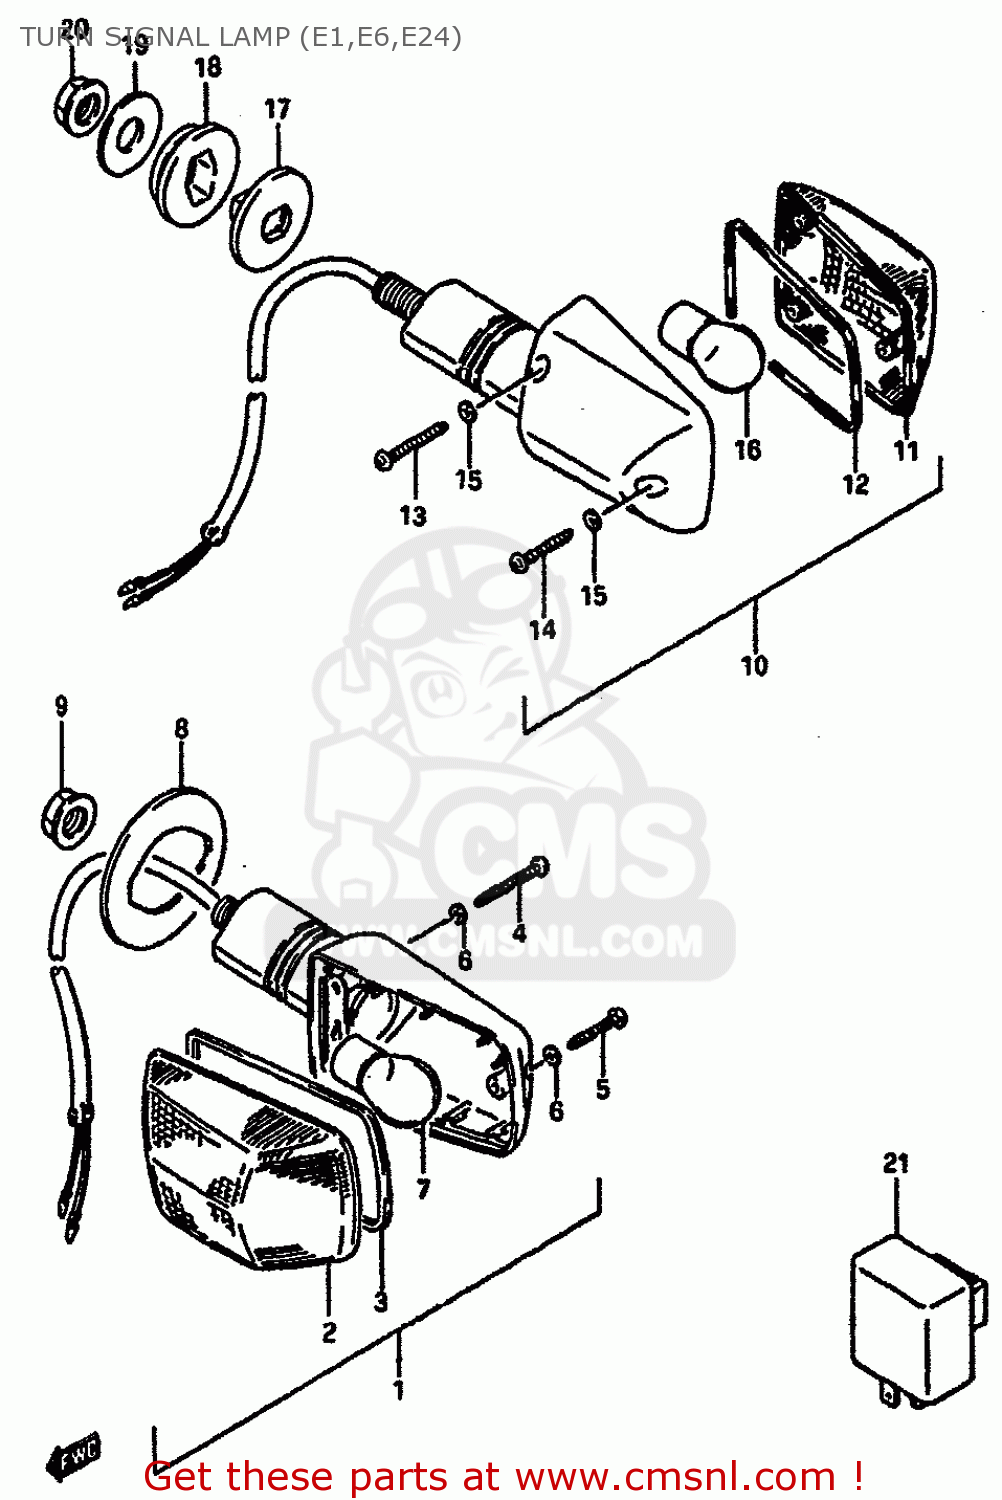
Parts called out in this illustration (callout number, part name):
1	LAMP ASSY,REAR TURN SIGNAL
2	LENS
3	GASKET (NAS)
4	SCREW(3X30)
5	SCREW
6	GASKET (NAS)
7	BULB(12V23W,STANLEY,A4577A)
8	GROMMET
9	NUT
10	LAMP ASSY,REAR TURN SIGNAL
11	LENS
12	GASKET (NAS)
13	SCREW(3X30)
14	SCREW
15	GASKET (NAS)
16	BULB(12V23W,STANLEY,A4577A)
17	SPACER
18	CUSHION
19	WASHER (10.2X27X1.6)
20	NUT
21	RELAY ASSEMBLY,TURN SIGNAL
